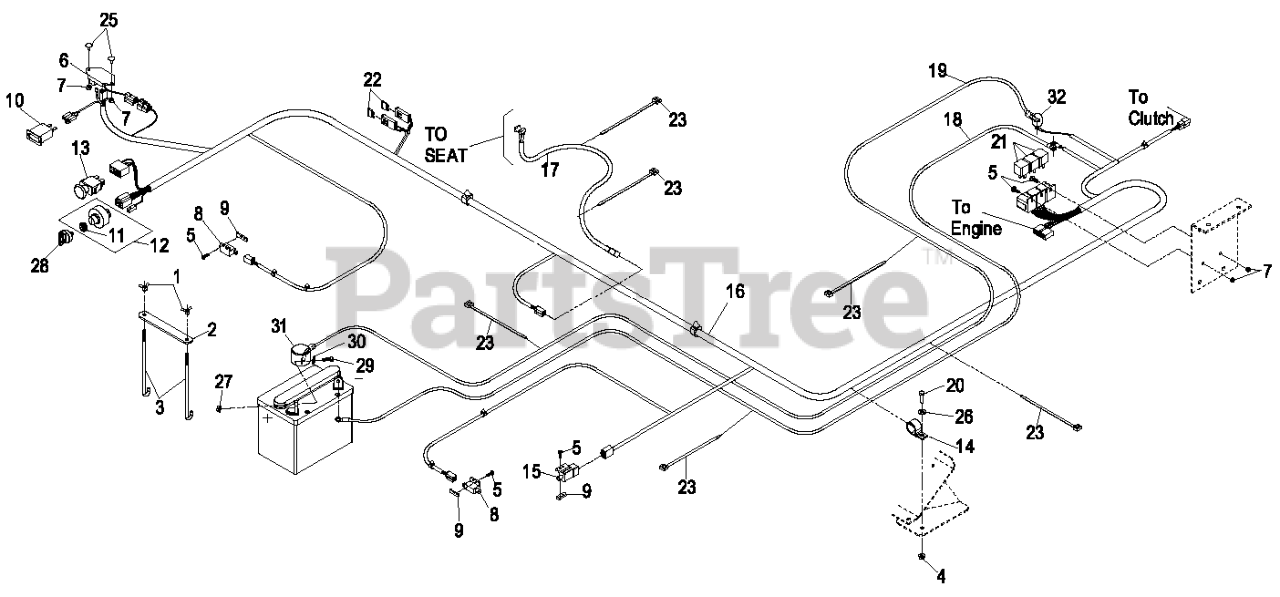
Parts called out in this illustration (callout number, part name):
1	WINGNUT
2	STRAP-HOLDDOWN, BATTERY
3	BOLT-HOLDDOWN
5	SCREW-PPH
6	MODULE-DELAY, SEAT
7	NUT-LOCK, NI
8	SWITCH-OPEN, NORMALLY
9	PLATE-TAPPED
10	METER-HOUR
11	NUT-SWITCH, IGNITION
12	ASM,SWITCH W/NUT
13	SWITCH-PTO
14	CLIP-LOOM
16	HARNESS,WIRE LXS AC
17	HARNESS-WIRING, SEAT
18	WIRE-GROUND
19	ASM,POSITIVE BATTERY CABL
20	SCREW-HH
22	FUSE-BLADE TYPE, 20 AMP
23	TIE-PLASTIC
25	BOLT-CARR
26	WASHER-PLAIN
28	KEY-IGNITION
29	SCREW-HH
30	WASHER-FLAT
31	INSULATOR-BATTERY
32	INSULATOR-SOLENOID
